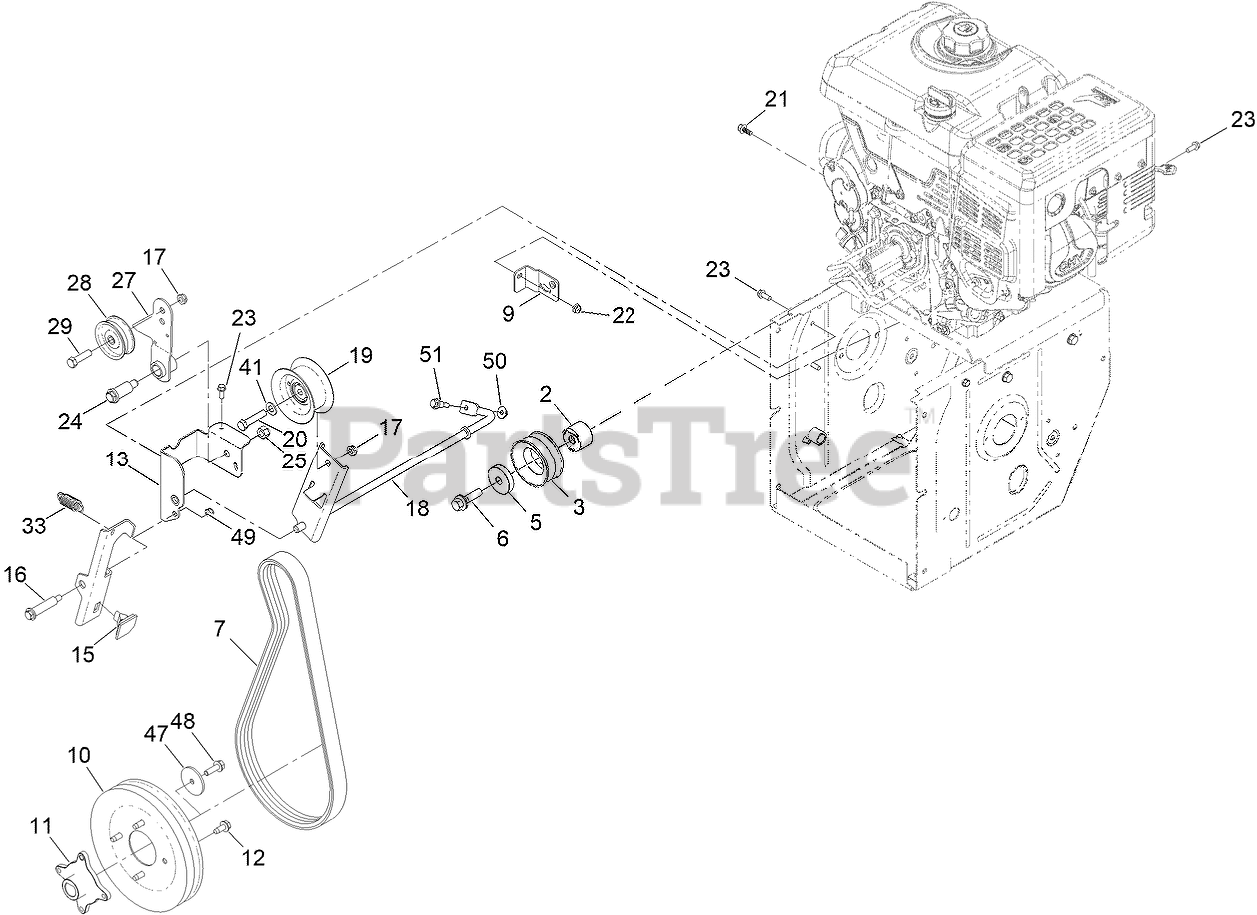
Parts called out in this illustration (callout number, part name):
2	PULLEY-SPACER
3	PULLEY-IMPELLER, DOUBLE SHEAVE
5	SUPPORT-PULLEY
6	BOLT-BLADE
7	BELT-V
9	BRACKET-CLUTCH, IMPELLER
10	PULLEY-IMPELLER, DOUBLE SHEAVE
11	HUB-PULLEY
12	SCREW-HWHTF
13	BRACKET-BRAKE, CLUTCH
15	PAD-BRAKE
16	BOLT-SHOULDER
17	NUT-HEX
18	ARM-CLUTCH, IMPELLER
19	PULLEY, IDLER
20	SCREW-HH
21	SCREW-HHF
22	NUT-HF
23	SCREW-HWH
24	BOLT-SHOULDER
25	NUT-HEX
27	ARM-IDLER, TRACTION
28	PULLEY-IDLER
29	SCREW-HH
33	SPRING-EXTENSION
41	WASHER-FLAT
47	WASHER-PLAIN
48	SCREW-HHF
49	NUT-HEX
50	NUT-HF
51	BOLT-SHOULDER
